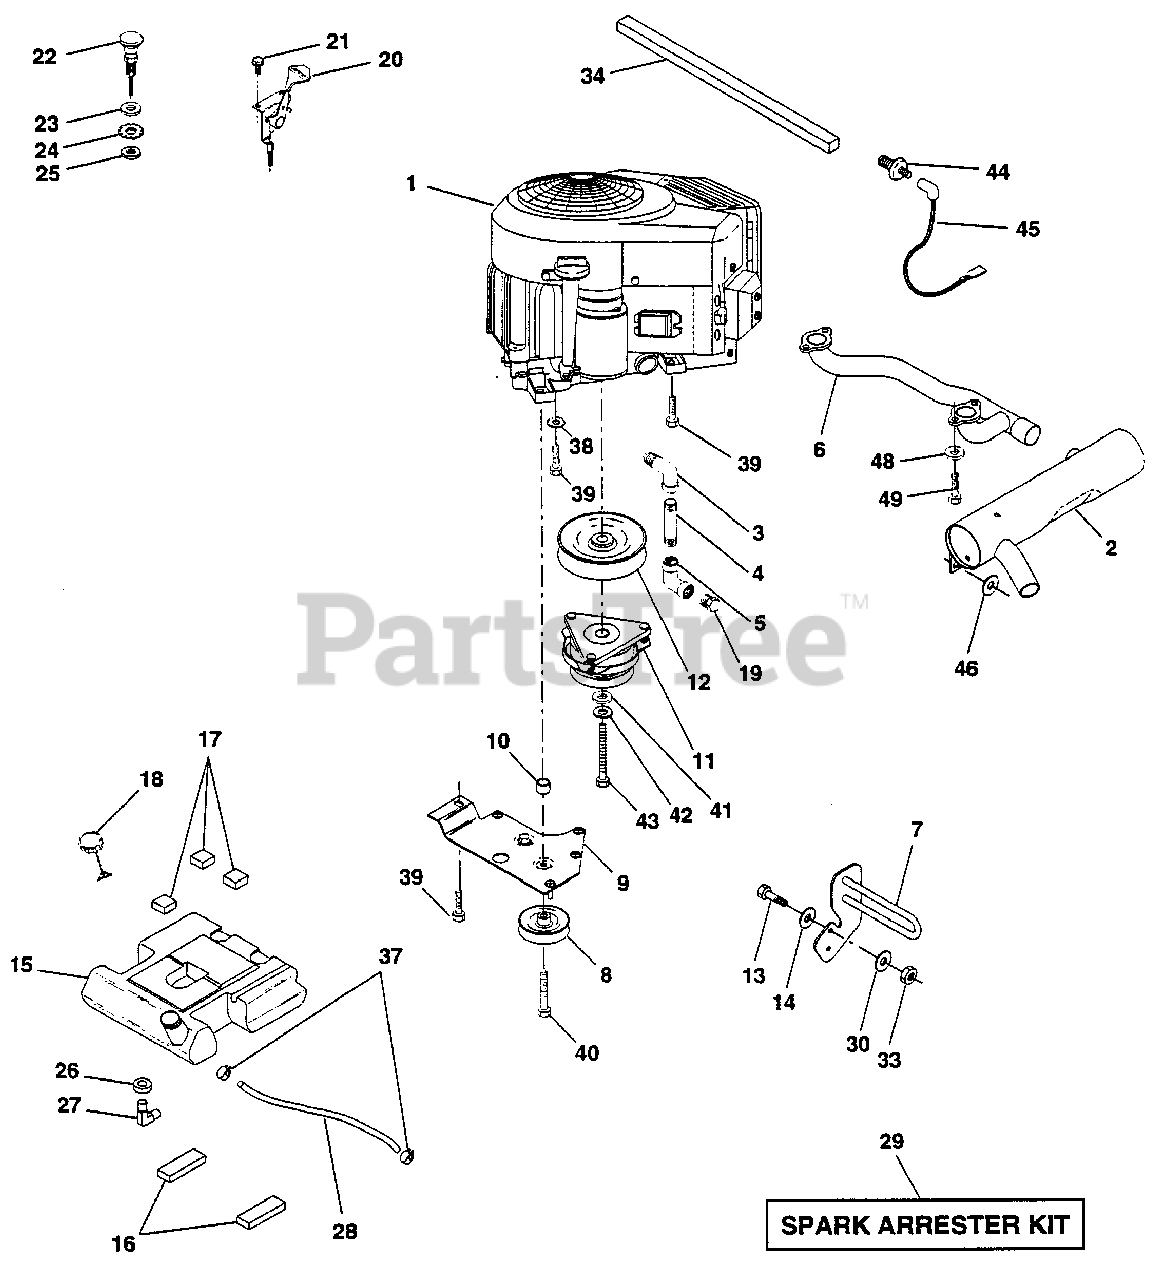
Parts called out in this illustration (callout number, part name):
1	Engine B&S, Model No. 351777
2	Muffler 20 Van/CV22
3	Elbow Street 3/8 NPT
4	Nipple Pipe 3/8NPT X 3 - 1/2
5	Elbow STD 90 Degree 3/8 - 18 NPT
6	Pipe Exhaust
7	Muffle Asm. Guard
8	Pulley V-Idler
9	Stop Keeper Asm VGT
11	Clutch Electric
12	Pulley Engine VGT Elect Clutch
13	Bolt Fin Hex 3/8 - 16 x 1-1/2
14	Washer Flat 13/32 x 7/8 x 14 Ga.
15	Tank Fuel W/Sym Vented
16	Pad Spacer
17	Pad Spacer
18	Cap Asm Fuel W/Sym Vented
19	Plug Oil Drain
20	Control Throttle
21	Screw Hex Thd Cut 1/4 - 20 X 5/8
22	Control Choke
23	Washer 13/32 X 13/16 x 16 Ga
24	Washer Ext Tooth 3/8
25	Nut Fin Hex 3/8 - 24 UNF
26	Bushing
27	Stem Tank Fuel
28	Fuel Line
29	Spark Arrester Kit
30	Washer 13/32 x 1-1/4 x 7 Ga.
33	Nut Lock Hex w/Ins 3/8 - 16
34	Strip Foam
35	Washer Lk 5/16
36	Bolt Socket Hd 8 x 1.25 x 20 mm
37	Clamp Hose
38	Lockwasher Ext Tooth 3/8
39	Screw Thdrol 3/8 - 16 X 1 - 1/2 TT
40	Screw Thdrol 3/8 - 16 X 3 - 1/4
41	Washer 1-1/2 OD X 15/32 ID X .250
42	Washer Lock 7/16
43	Bolt Hex 7/16-20 X 4-1/4 Ga 5
44	Switch Engine Oil Pressure
45	Wire Lead Sentry Oil Vang
46	Washer 13/32 x 1 x 16 Ga.
